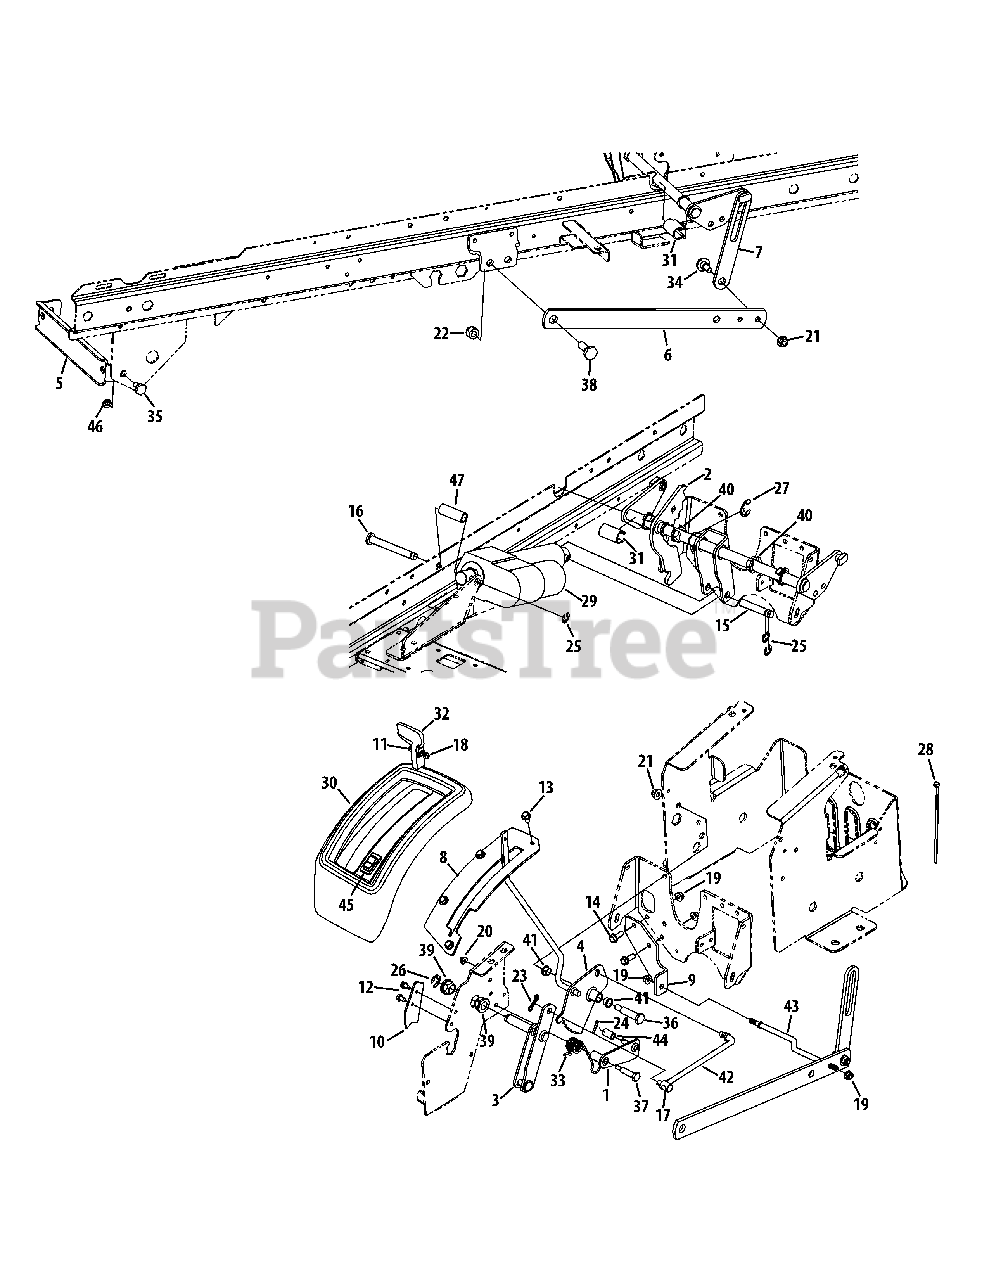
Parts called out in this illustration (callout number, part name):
1	Hub Lift Assembly
2	Electric Shift Assembly
3	Deck Height Adjustment
4	Lift Lever Bracket Assembly
5	Front Hanger Bracket
7	Lift Link Plate
9	Sway Bar Mount Bracket
10	Bearing Stop Plate
11	Machine Screw, #10-24 x .625
12	Hex Washer Screw, 1/4-20 x .500
13	Hex Washer Screw, 5/16-18 x .625
14	Hex Washer Screw, 5/16-18 x .875
15	PIN, .50 x 3.5
16	Clevis Pin, .50 x 4.0
17	Ferrule, 3/8-24 x .375
18	Hex Lock Nut, #10-24
19	Flange Lock Nut, 5/16-18
20	Flange Lock Nut, 1/4-20
21	Flange Lock Nut, 3/8-16
22	Hex Lock Nut, 1/2-13
23	Bow-Tie Cotter Pin, 72
24	Cotter Pin, .125 x .75
25	E-Ring, .500
26	E-Ring, .625
27	E-Ring, .875
28	Cable Tie, 3/16 x .05 x 7.4
29	Lift Actuator
30	Lift Cover
32	Electric Lift Knob
33	Torsion Spring
34	Shoulder Screw, 3/8-16 x .562 x .360
35	Shoulder Screw, 1/2 x .29
36	Shoulder Screw, .498 x 1.635
37	Shoulder Screw, .374 x 1.375
38	Shoulder Screw, 1/2-13 x .625 x .36
39	Hex Flange Bearing
40	Hex Flange Bearing, .78
41	Flange Bearing, .500 x .34
42	Electric Lift Rod Adjuster
43	Anti-Sway Deck Rod
44	Spacer, .35 x .5 x .851
45	Lift Switch
46	Jam Lock Nut, 3/8-16
47	Spacer, .55 ID x .75 OD x 2.06
